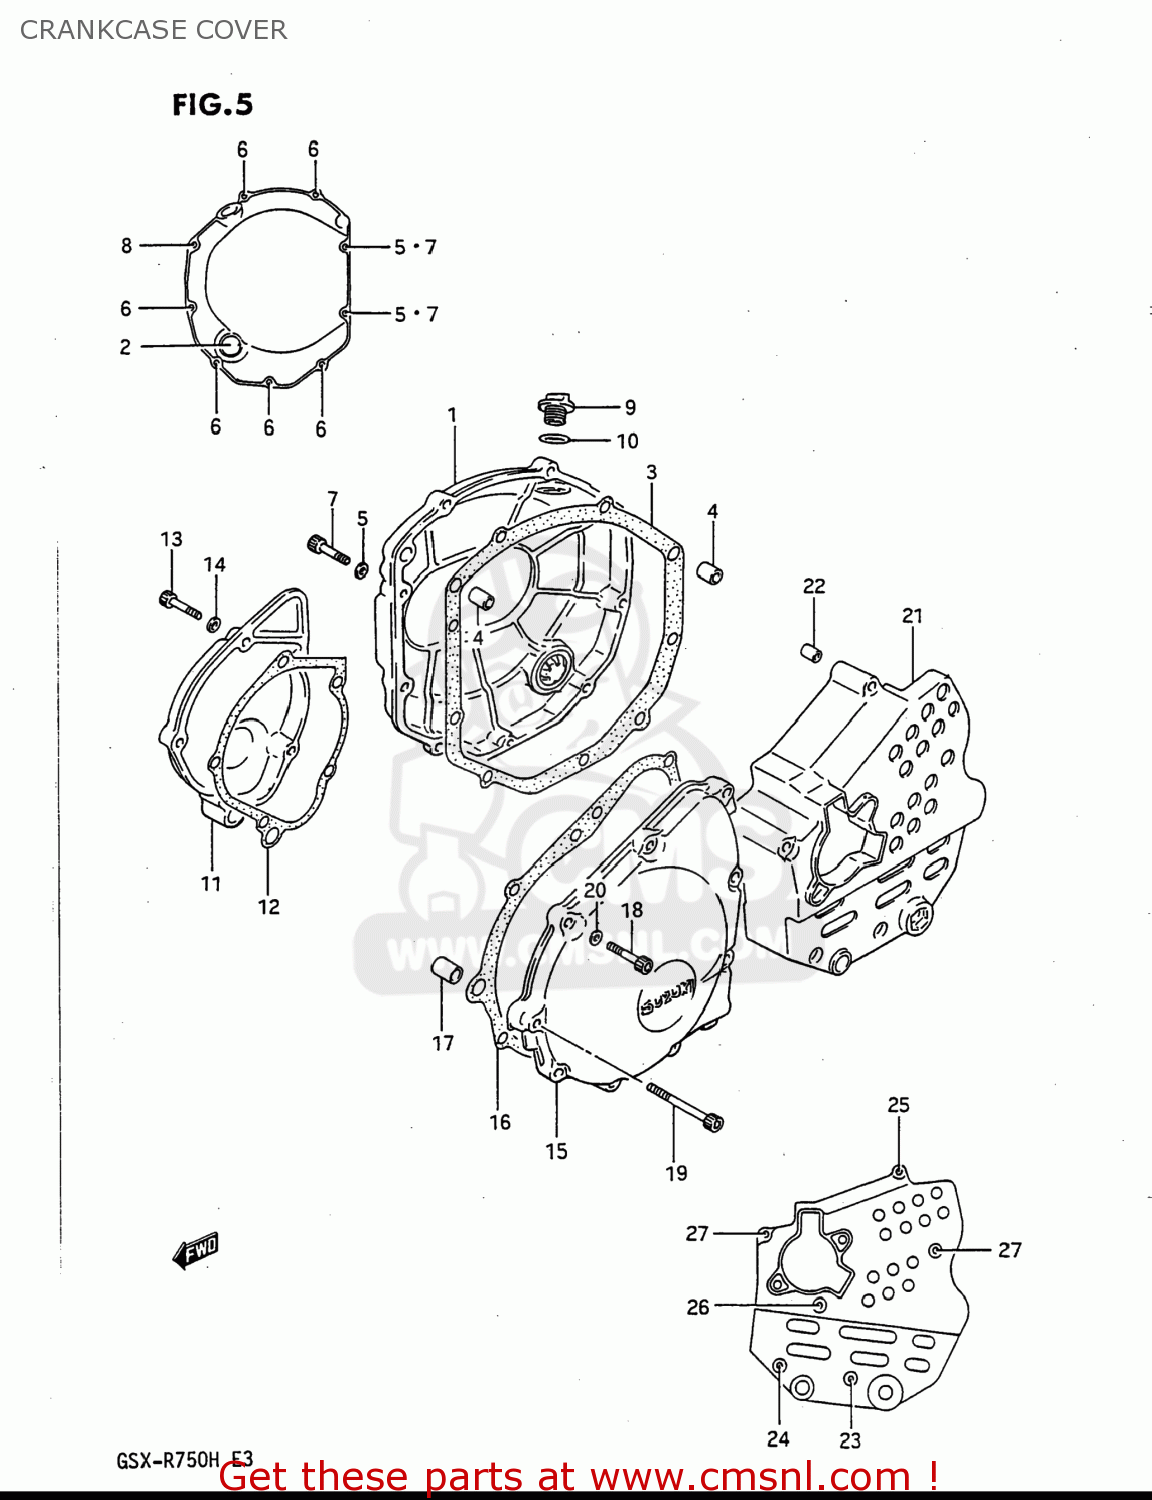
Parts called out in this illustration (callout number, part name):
1	COVER,CLUTCH
2	LENS,OIL LEVEL CHECK
3	GASKET,CLUTCH COVER (MCA)
4	PIN
5	GASKET(5.8X11X1.2) (NAS)
6	BOLT
7	BOLT
8	BOLT
9	PLUG
10	O RING(D:3.1,ID:16.8)
11	COVER,SIGNAL GENERATOR
12	GASKET,SIGNAL GENERATOR COVER (NAS)
13	BOLT
14	GASKET(5.8X11X1.2) (NAS)
15	COVER,STARTER GEAR
16	GASKET,STARTER GEAR COVER (MCA)
17	PIN (11X20)(SUS)
18	BOLT
19	BOLT
20	GASKET(5.8X11X1.2) (NAS)
21	COVER,SPROCKET
22	PIN
23	BOLT
24	BOLT
25	BOLT
26	BOLT
27	BOLT
